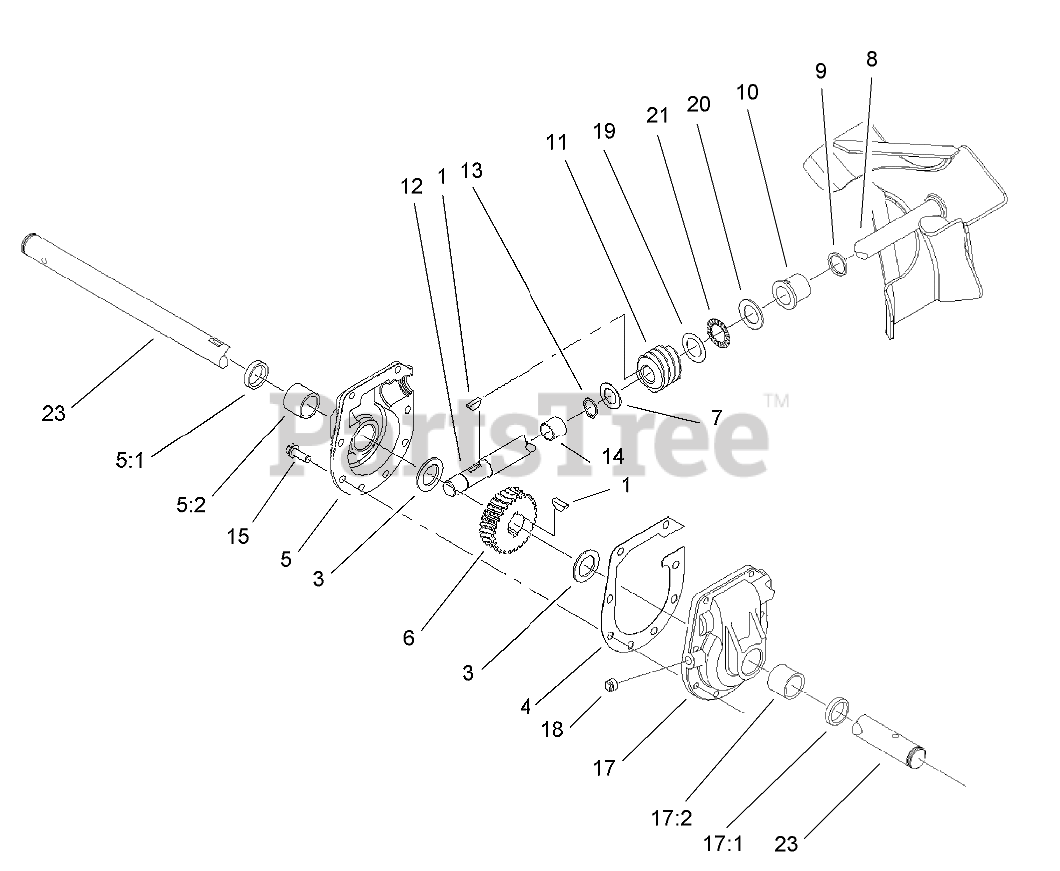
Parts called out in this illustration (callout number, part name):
1	KEY-WOODRUFF
3	WASHER-THRUST
4	GASKET-CASE, GEAR
5	RH BUSHING CASE ASM
5:1	SEAL-OIL
5:2	BUSHING
6	GEAR-WORM, 27T
7	WASHER-THRUST
8	IMPELLER ASM
9	RING-QUAD
10	BUSHING-INPUT
12	KEY-WOODRUFF
13	Ring-Snap
14	BUSHING
15	SCREW-TAPTITE
17	LH BUSHING CASE ASM
17:1	SEAL-OIL
17:2	BUSHING
18	PLUG-PIPE, SQH
19	WASHER-THRUST
20	WASHER-THRUST
21	BEARING-THRUST
23	SHAFT-AUGER
